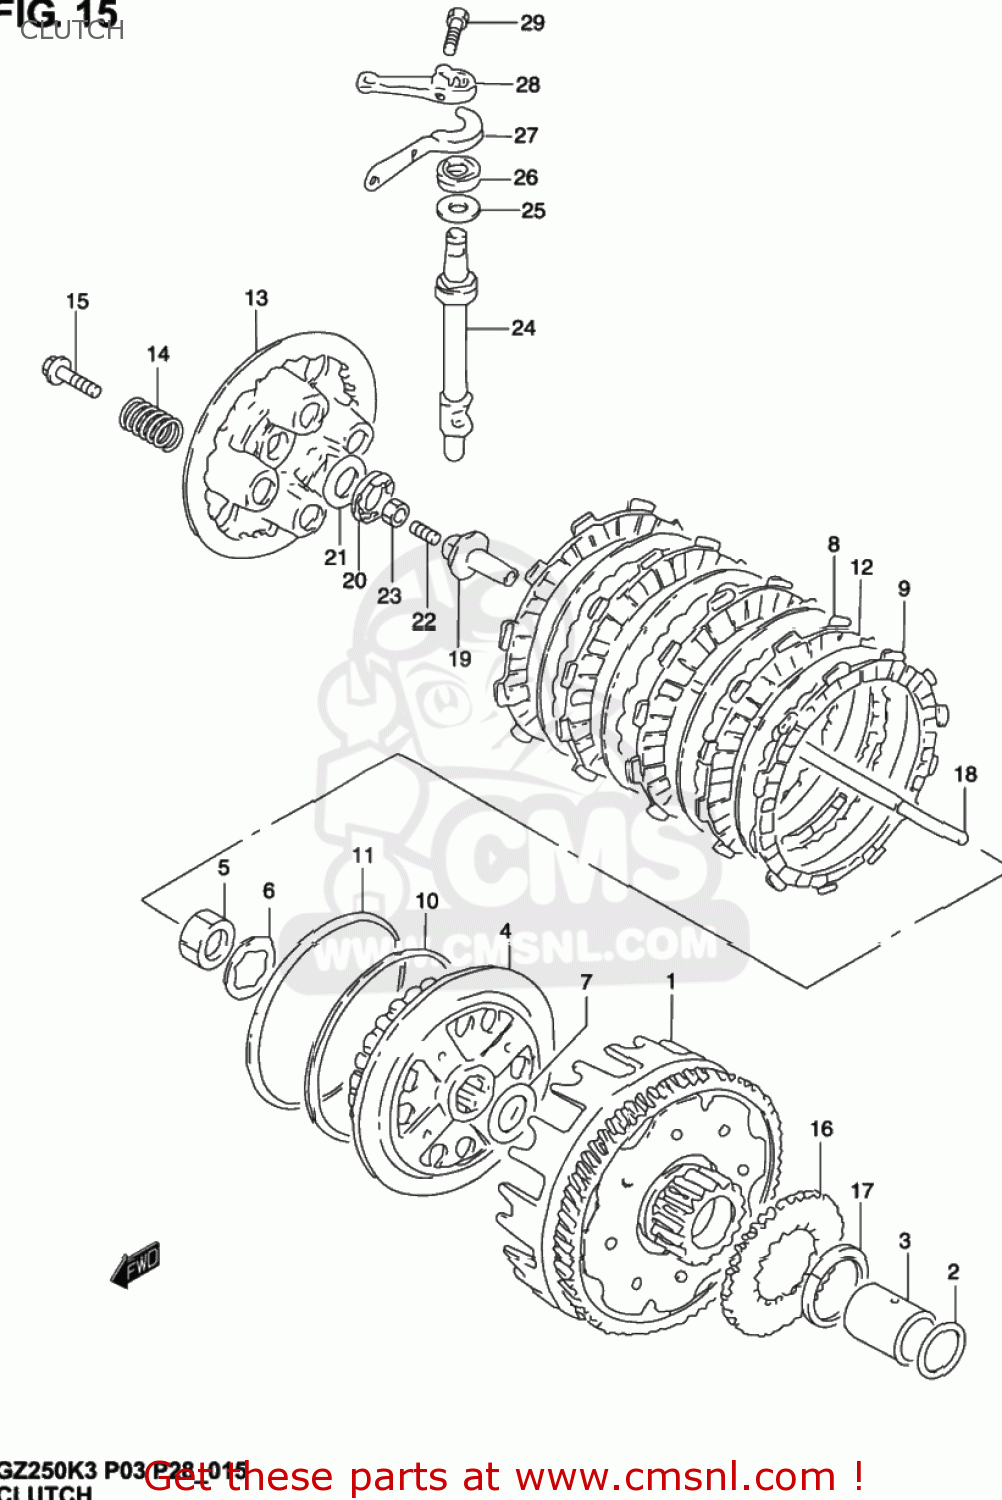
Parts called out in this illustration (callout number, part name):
1	GEAR ASSY,PRI DRIVEN
2	WASHER
3	SPACER(22X28X37.5)
4	HUB,CLUTCH SLEEVE
5	NUT
6	WASHER,LOCK
7	WASHER
8	PLATE,CLUTCH DRIVE (NAS)
9	PLATE,CLUTCH DRIVE(T:3.5) (NAS)
10	SEAT,WAVE WASHER(T:1.4)
11	WASHER
12	PLATE,CLUTCH DRIVEN(T:1.6) (NAS)
13	DISC,CLUTCH PRESSURE
14	SPRING,CLUTCH
15	BOLT(6X16)
16	GEAR,OIL PUMP DRIVE
17	CIRCLIP
18	ROD,CLUTCH PUSH
19	PIECE,CLUTCH PUSH
20	BEARING(15X28X2)
21	WASHER(15.5X28X1)
22	SCREW(6X25)
23	NUT
24	CAMSHAFT,CLUTCH RELEASE
25	WASHER(14.5X22X1)
26	OIL SEAL
27	PLATE,CLUTCH RRS CAMSHAFT SEAL
28	ARM,CLUTCH RELEASE
29	BOLT
